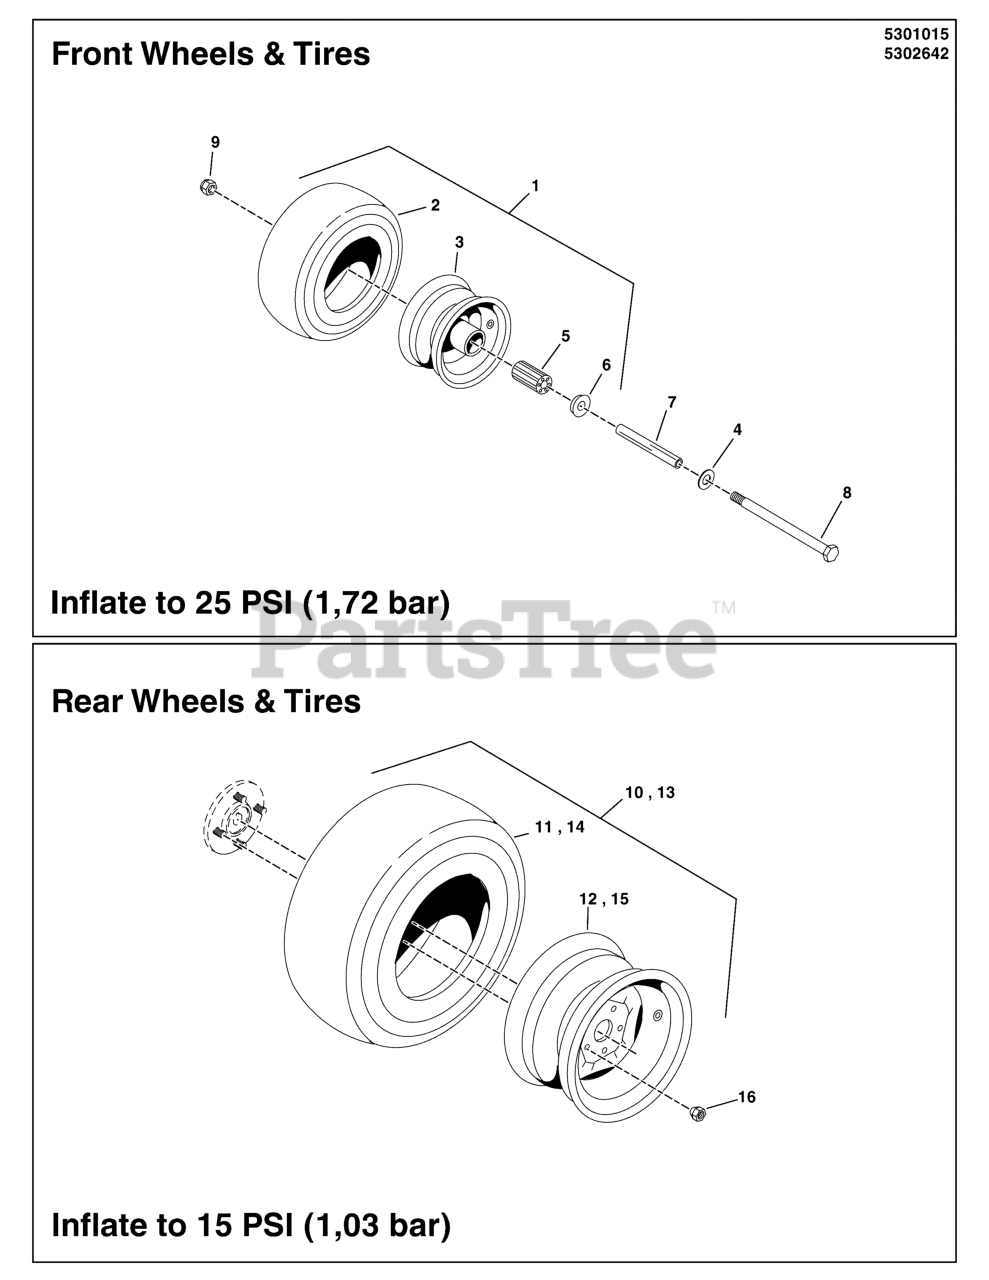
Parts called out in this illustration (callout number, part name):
1	WHEEL, CASTER, 11 X 4.0-5 SILVER BEAD LO
2	TIRE, 11 X 4.0-5
3	WHEEL FOR 11X4.0-5 TIRE ASSM
4	WASHER, 1/2 SAE
5	BEARING, CASTER WHEEL, 11X4-5 BEAD LOCK
6	RETAINER, BEARING
7	CASTER AXLE DDSH
8	BOLT, 1/2-13 X 7 GD8 YZ
9	NUT, Hex Flange, Nylock, 1/2-13
10	TIRE ASM, 20 X 7 - 10, TURF MASTER
11	TIRE, 20 X 7 -10 NHS, TURF MASTER
12	WHEEL, 10 X 6.00 4/4 SOLID, F237
13	TIRE ASM, REAR, 20 X 10.0 X 10
14	TIRE, REAR, 20 X 10.0 X 10
15	WHEEL, 10X7.00 4/4 SOLID F237 2.625 OS
16	NUT, 1/2-20, FOR WHEEL BOLT SILVER
